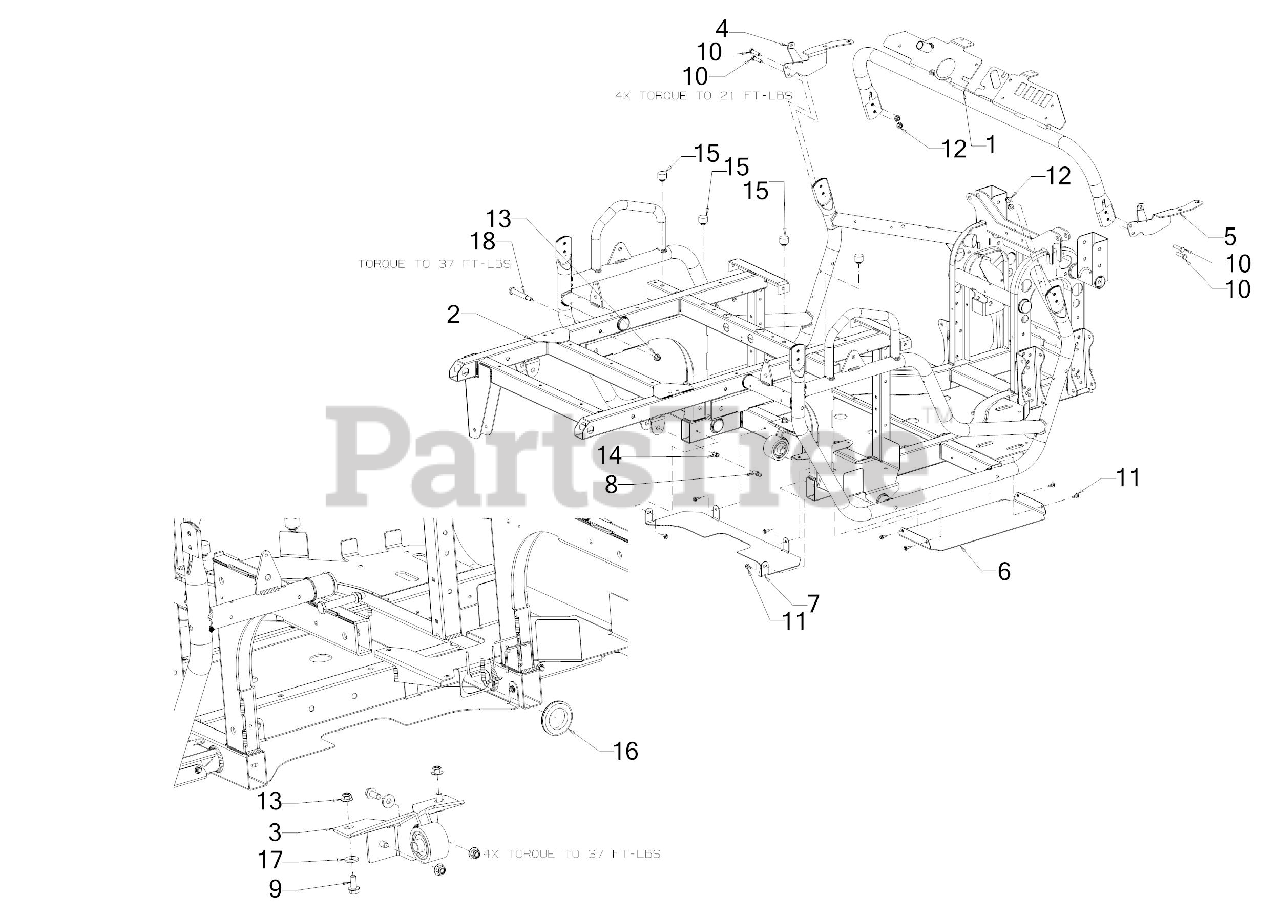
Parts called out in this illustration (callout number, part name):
1	DASH FRAME ASSEMBLY
2	FRAME ASSEMBLY
3	SWING ARM PIVOT BUSHING ASSEMBLY
4	HOOD FRAME BRACKET (LH)
5	HOOD FRAME BRACKET (RH)
6	SIDE SKID PLATE
7	SKID PLATE BRACKET
8	BALL STUD 5/16-18
9	SCREW 3/8-16 x .875 GR5
10	SCREW 5/16-18 x 1.25 GR5
11	SCREW M6-1 x .625
12	FLANGE LOCK NUT 5/16-18
14	NUT RIVET 5/16-18
15	RUBBER BUMPER
16	RUBBER GROMMET
18	SHOULDER SCREW
